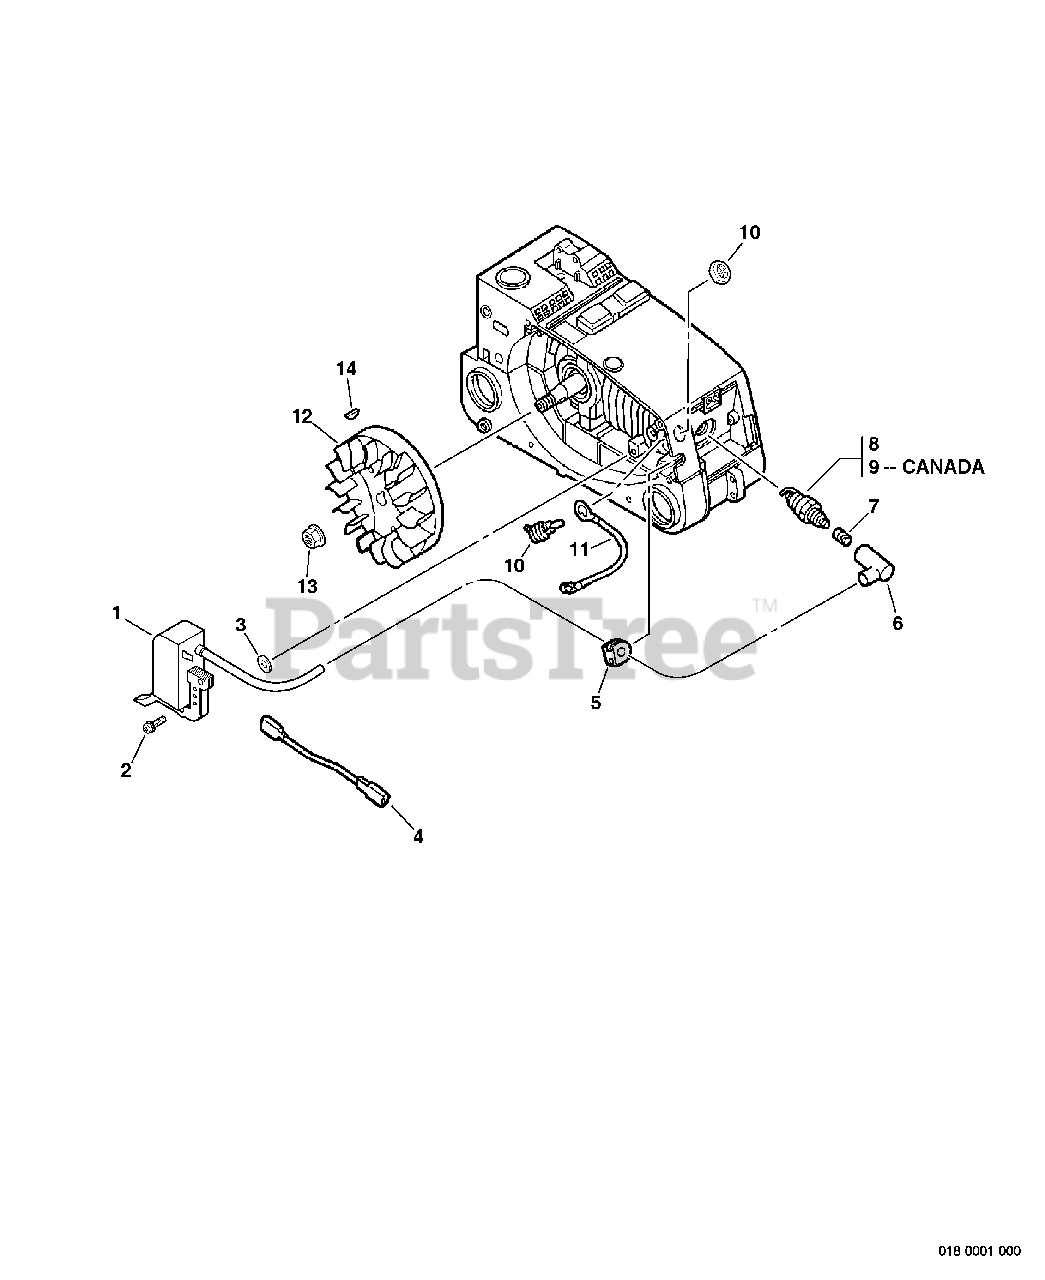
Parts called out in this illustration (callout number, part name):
1	COIL, IGNITION
2	SCREW 5×22
3	WASHER 5.2×12×3
4	LEAD - IGNITION L= 95
6	CAP, SPARK PLUG
7	TERMINAL, SPARK PLUG
8	SPARK PLUG - BPM8Y
9	SPARK PLUG - BPMR8Y
10	SWITCH, ON-OFF
11	LEAD - GROUND L= 100
12	FLYWHEEL
13	NUT, FLANGE M8
14	KEY, WOODRUFF
